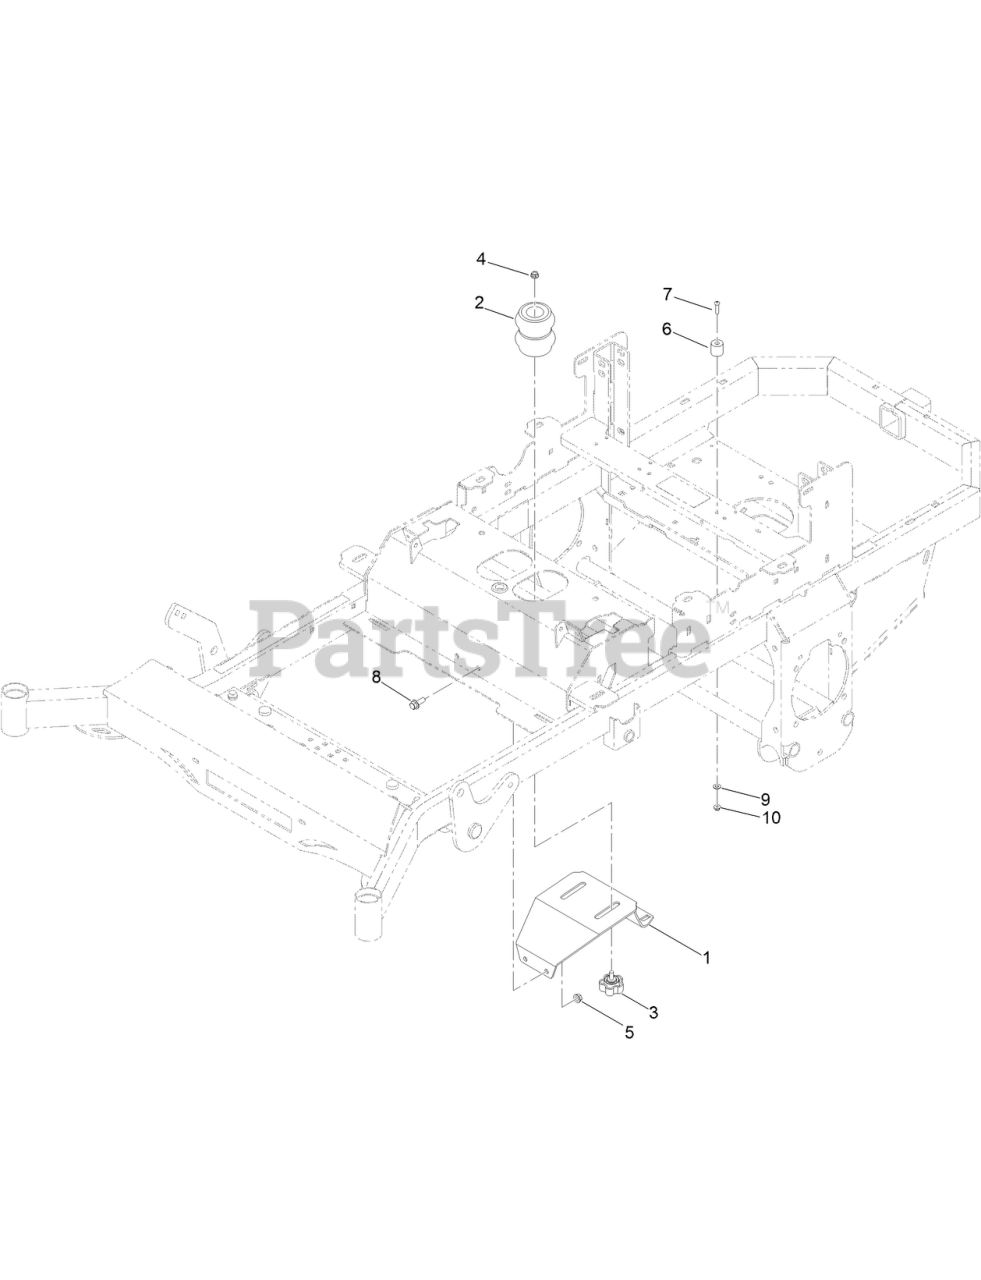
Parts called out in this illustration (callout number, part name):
1	MWR SEAT SUSP BRKT BLACK
2	SRT RR SUSP AND SEAT FT ELASTOMER TCB-3
3	5/16-18X3/4 SL 5-LOBE MALE KNOB 1.90 DIA
5	3/8-16 HEX FLANGE NUT W/SERR ZINC YELLOW
6	HOOD REST RUBBER BUMPER
7	1/4-20 X 1 BUTTON SOCKET C/S 18-8 SS
8	SCREW-HHF
9	WASHER-FLAT
10	NUT-HF
